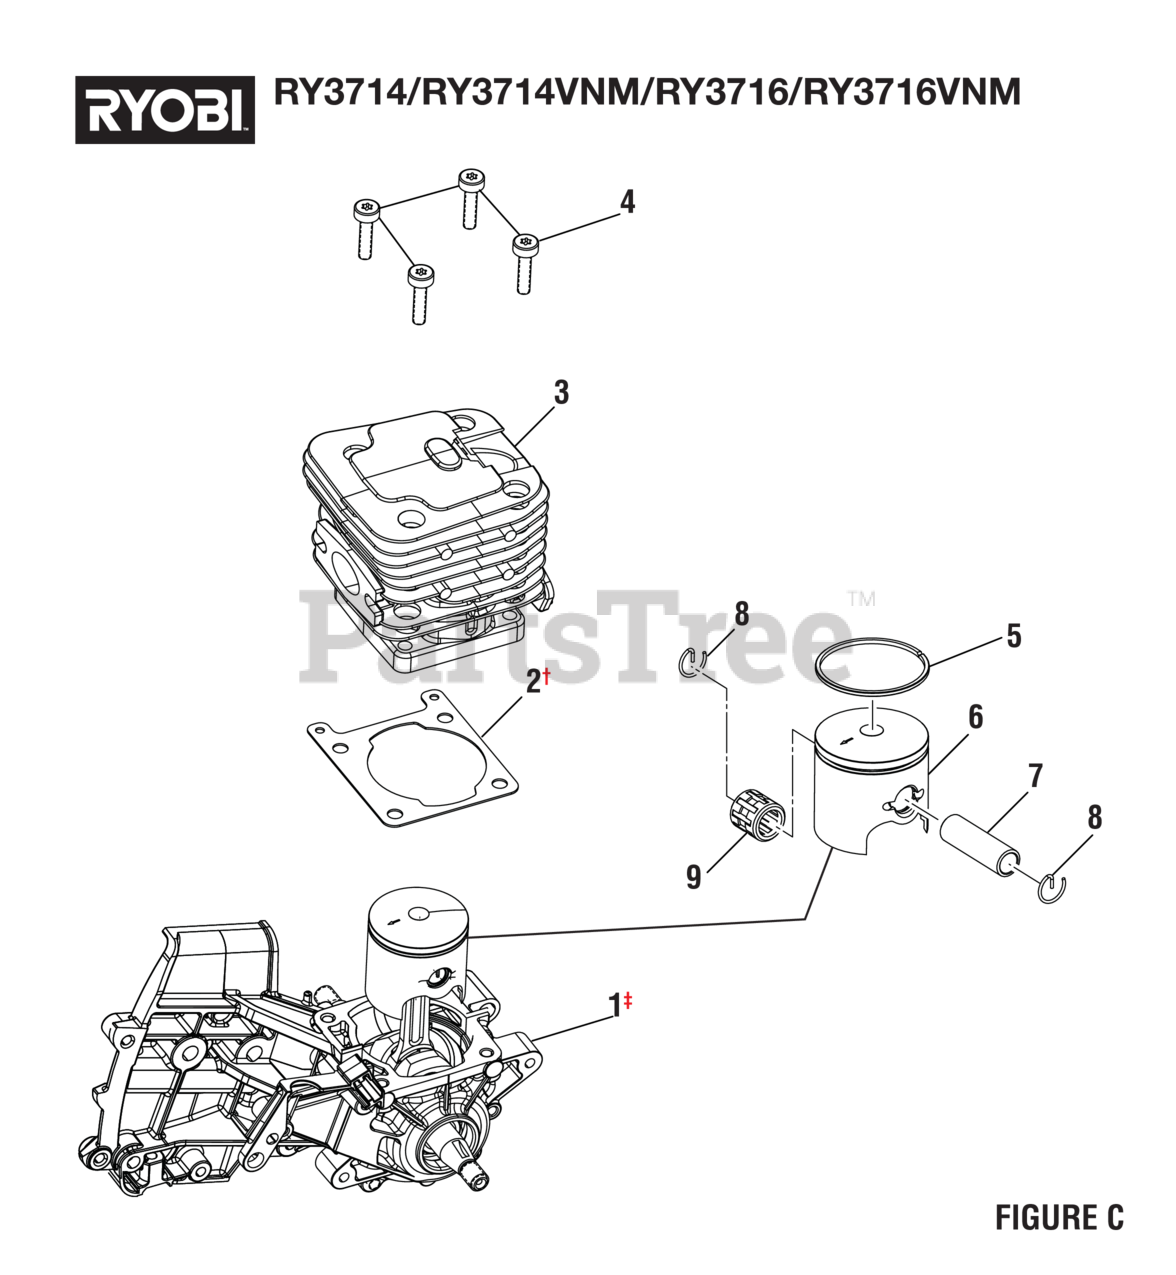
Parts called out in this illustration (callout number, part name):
1	Crankcase & Crankshaft Assembly
2	Crankcase Gasket
4	Cap Screw (M5 x 20 mm, T25 Torx Soc. Hd.)
5	Piston Ring
7	Piston Pin
8	Piston Pin Clip
9	Needle Bearing
